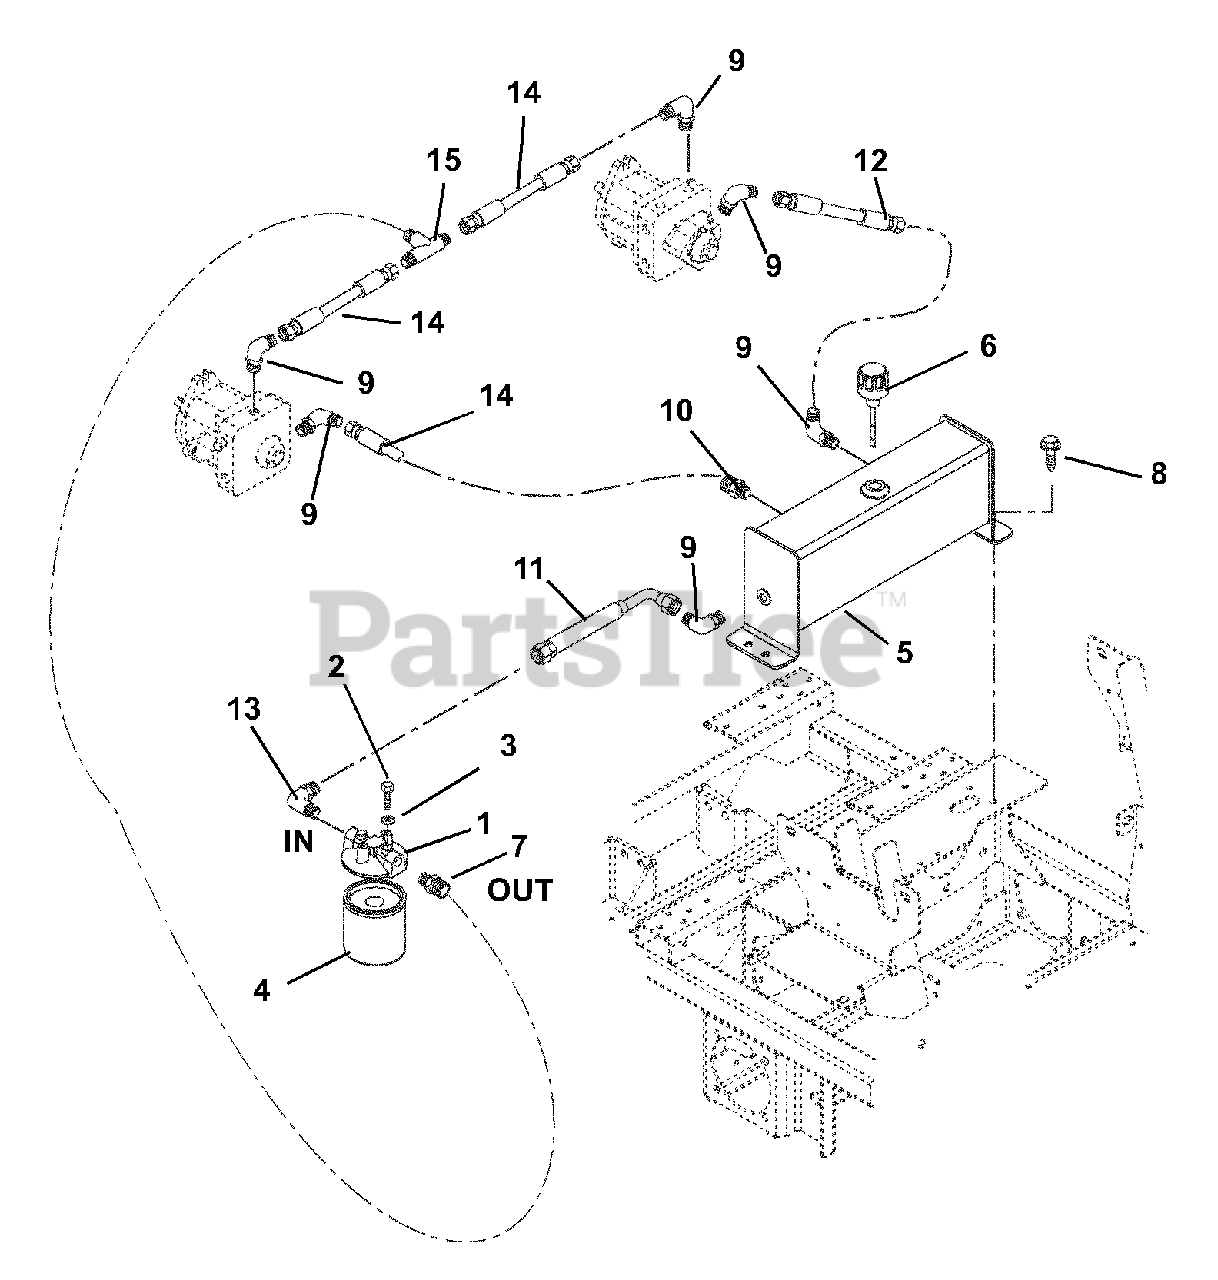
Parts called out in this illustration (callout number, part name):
1	Filter Housing
2	Bolt-Hex .25-20 x .50 Grade 5
3	Washer-Locking .25 x .062
4	Filter Element
5	Body, Hydraulic Tank
6	Breather, Dipstick
7	Adapter-Hydraulic Steel
8	Screw-Tapping .38-16 x .75 Hex Washer Head
9	Adapter, Hydraulic Elbow
10	Adapter, Hydraulic Steel
11	Hose-Hydraulic Valve to Tank
12	Hose, Hydraulic
13	Adapter, Elbow 90 Degree
14	Hose, Hydraulic .50
15	Fitting Hydraulic Tee
